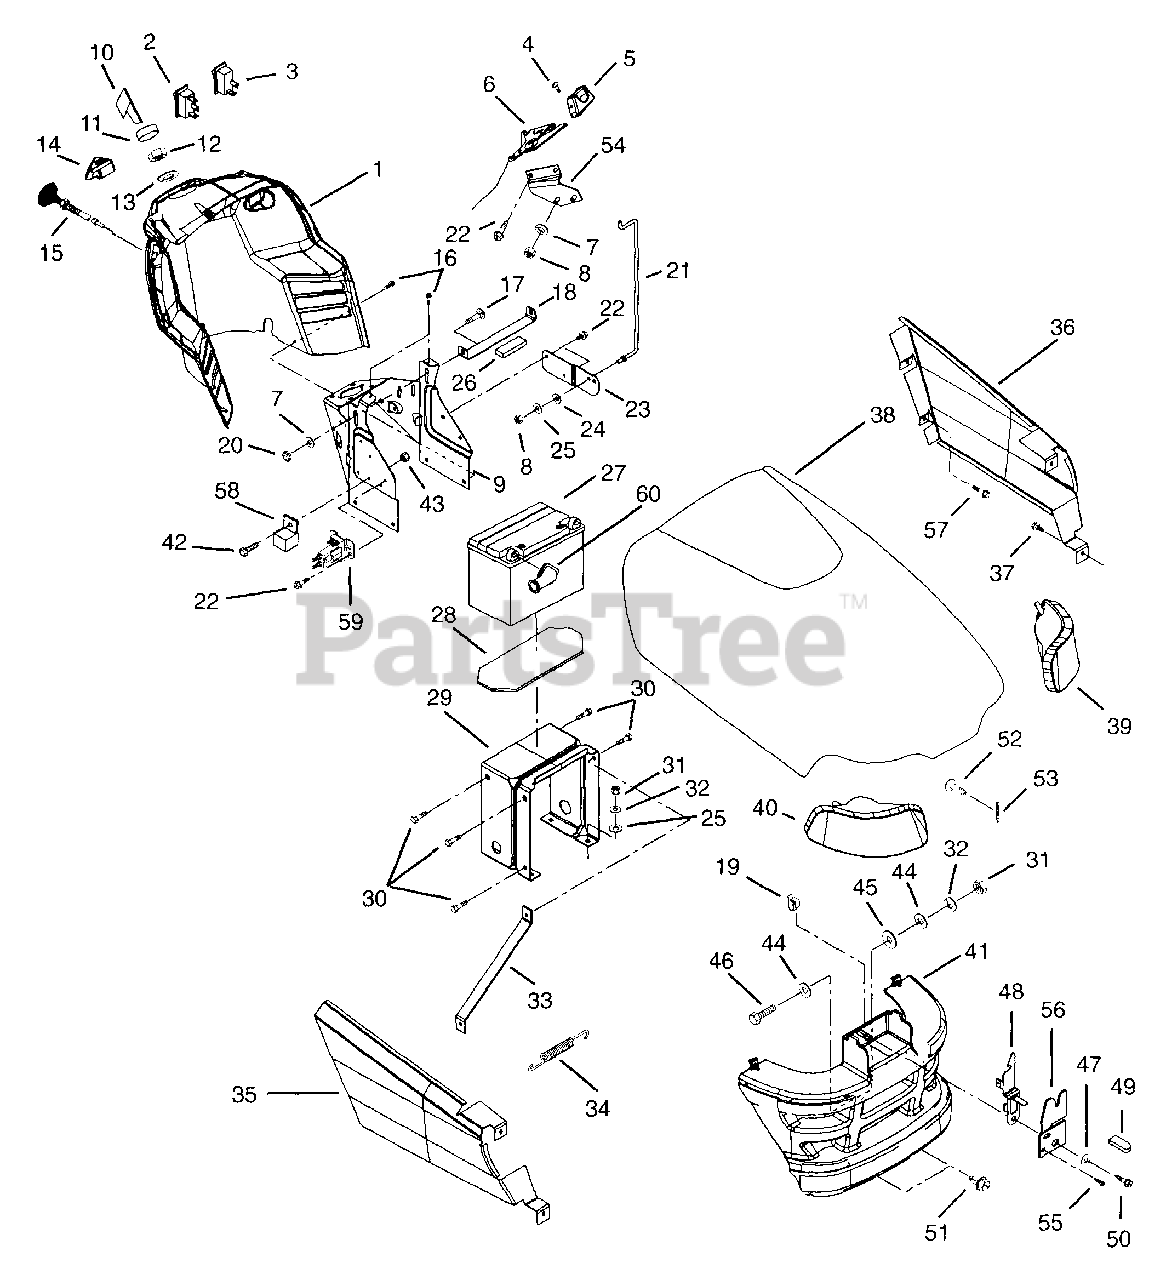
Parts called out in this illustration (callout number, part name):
1	DASH
2	SWITCH - CRUISE
3	SWITCH - LIGHT
4	SCR-SET 10-24X.38 UNC-3A
5	KNOB - THROTTLE
6	THROTTLE CONTROL-B&S
7	WSHR-FL-STL .323X.625X.062 YWZ
8	@NUT-LK-CTR .25-20 YWZC
9	SUPPORT - DASH - TOP
10	KEY -W/CAP
11	CAP - IGNITION SWITCH
12	NUT- PANEL .562-24 GRECO
13	WSHR-LK-INT .625X.045 YWZC
14	PTO KNOB/ SHAFT ASSY
15	CHOKE CABLE
16	SCR-TAP 10-24X.484 HWH TR
17	@BLT-RDHDSQNK .31-18X.75 G5YZ
18	HOLDDOWN - BATTERY
19	CLIP-HARNESS TINNERMAN
20	@NUT-LK-NYL .312-18 YWZC
21	ROD - HOOD PROP
22	@SCR-TAP .25-20X.37 HWH YWZ TR
23	MOUNT - PROP ROD
24	WAVE WASHER .390X.655X.110
25	@WSHR-FL-STL.312X.734X.065 YWZ
26	PAD, FOAM
27	BATTERY W/TUBE
28	RUBBER PAD
29	SUPPORT DASH BASE
30	SCR-TAP .312-18X.50 HWH TR BL
31	@NUT-HEX .31-18 YWZC
32	WSHR-LK .312X.097 HVY YWZC
34	SG-TENS .035X.45X2.75 WLD 3.5
35	SIDE PANEL- RH
36	SIDE PANEL- LH
37	SCR-TAP 12-16X.500 HI-LOTPHBL
38	HOOD WITH DECALS
39	HEADLIGHT- LH
40	HEADLIGHT- RH
41	GRILLE
42	BLT-HEX 10-24X1.25 PL
43	@NUT-LK-NYL 10-24 W/INSRT YWZC
44	WSHR-FL-STL .328X1.0X.094 YWZC
45	WSHR-FL-NYL .390X1.000X.062
46	@BLT-HEX .31-18X1.00 GR5 YWZC
47	WSHR-FL-STL .281X1.250X.048 BL
48	HOOD LATCH
49	GRIP .062 X .375 X 1.000 RE
50	SCR-TAP 12-24X.50 HWH TR BLACK
51	SCR-TAP .312-18X.50 HWH TR BL
52	PIN, CLEVIS .243/.248X1.50 YWZ
53	@PIN-CTR .09X.75 EXTPRSQCT YWZ
54	BRACE-THROTTLE CONTROL
55	SCR-TAP 10-12X.50 CRPH PL A BL
56	LOCATOR- HOOD
57	SCR-TAP 10-16X.62 SLPH AB YWZC
58	RELAY
59	SOLENOID
60	INSULATOR
